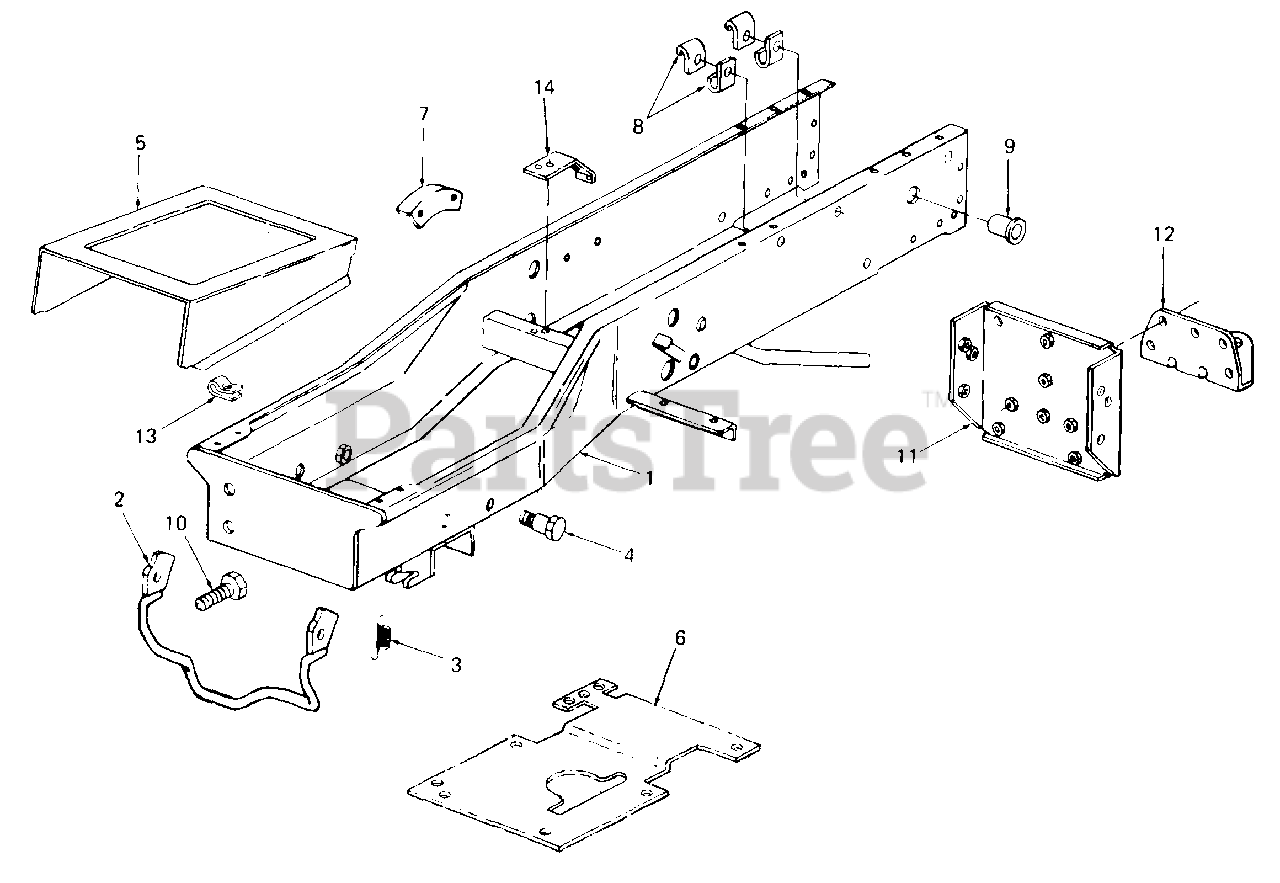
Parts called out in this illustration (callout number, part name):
3	Spring, Latch
4	Bolt, Shoulder
5	Cover, Frame w/Graphic
7	Bracket Height Indicator
8	Clip Cable
9	Bushing, Snap
10	Screw, Adjustment, 1/2-20 x 1.0 Lg GR5
13	Nut, Speed
14	Bracket, Switch
